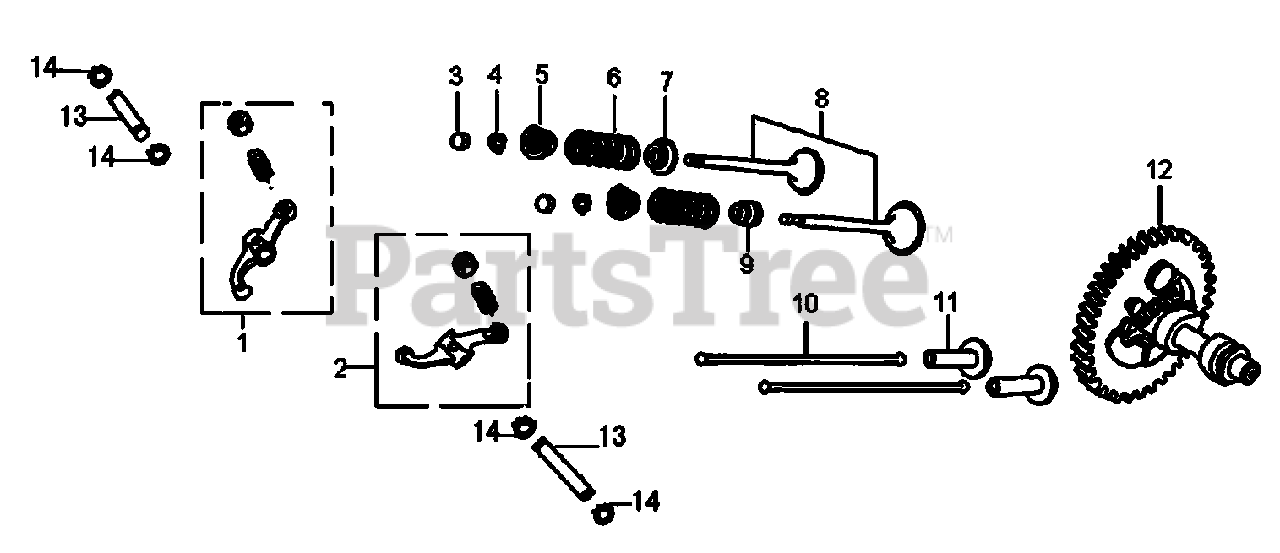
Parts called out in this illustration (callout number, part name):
1	ROCKER ARM ASSY.
2	ROCKER ARM ASSY.
3	VALVE, ROTATOR
4	VALVE LOCKER
5	RETAINER, VALVE SPRING
6	SPRING, VALVE
7	SEAT, VALVE SPRING
8	VALVE ASSY.
9	SEAL, VALVE STEM
11	LIFTER, VALVE
12	CAMSHAFT ASSY
13	SHAFT, ROCKER ARM
